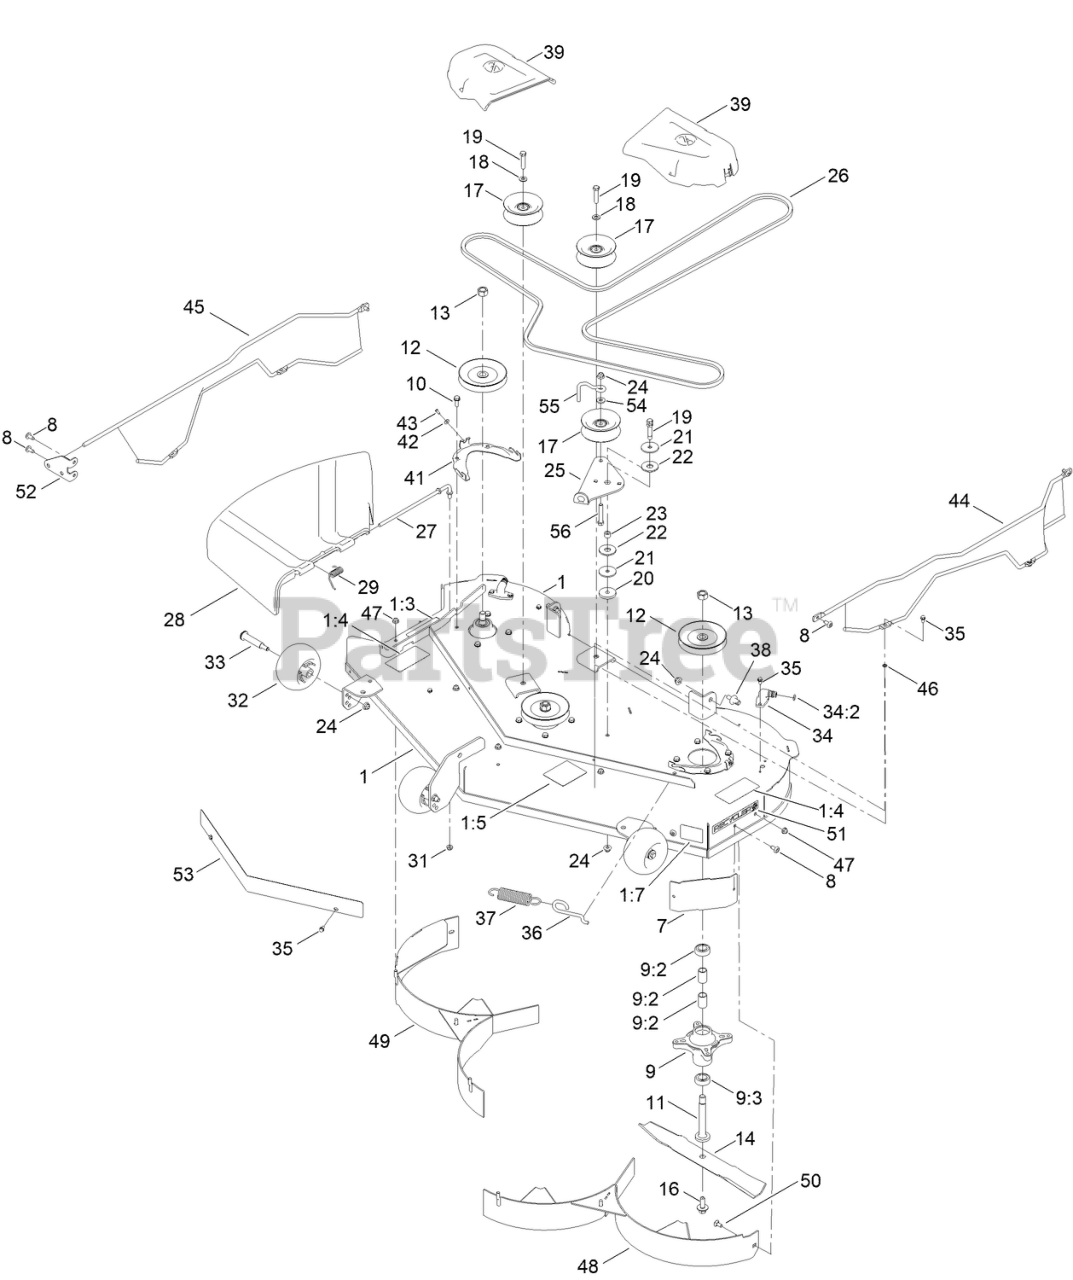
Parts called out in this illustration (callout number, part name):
1	50 INCH DECK AND DECAL ASM
1:3	DECAL-DANGER
1:4	DECAL-DANGER, DECK
1:5	DECAL-ROUTING, BELT
1:7	DECAL-SCALP, ANTI
7	BAFFLE-CORNER
9	SPINDLE ASM
9:2	SPACER
9:3	BEARING-BALL
10	SCREW-TAPTITE
11	SHAFT-SPINDLE
12	PULLEY
13	Nut-Hex
14	BLADE-MULCH, 17.50 INCH
16	BOLT-BLADE, SEMS
17	PULLEY-IDLER, FLAT
18	WASHER-FLAT
19	SCREW-HH
20	WASHER-PLAIN
21	Washer
22	WASHER-FRICTION, COMPOSITE
23	SPACER
24	NUT-HF, NI
25	ARM-IDLER
26	V-BELT
27	ROD-PIVOT
28	DEFLECTOR-DISCHARGE
29	SPRING-TORSION
31	NUT-HEX
32	ROLLER-SCALP, ANTI
33	BOLT-SHOULDER
34	FITTING-WASHOUT
34:2	O-RING
35	SCREW-HWH
36	HOOK-RETURN SPRING
37	SPRING-EXTENSION
38	PIN-DECK
39	COVER-BELT
41	BRACKET-COVER, BELT
42	WASHER-PLAIN
43	SCREW
44	LEFT GUARD ASM
45	RIGHT GUARD ASM
46	NUT-RETAINING
47	NUT-HF
48	50IN BAFFLE ASM
49	50IN BAFFLE ASM
50	BOLT-CARR
51	DECAL-RECYCLER
52	PLATE-MOUNT, GUARD
53	SHIELD-FRONT
54	SPACER-HUB, BLOWER
55	BELT GUIDE - IDLER
56	SCREW-HH
